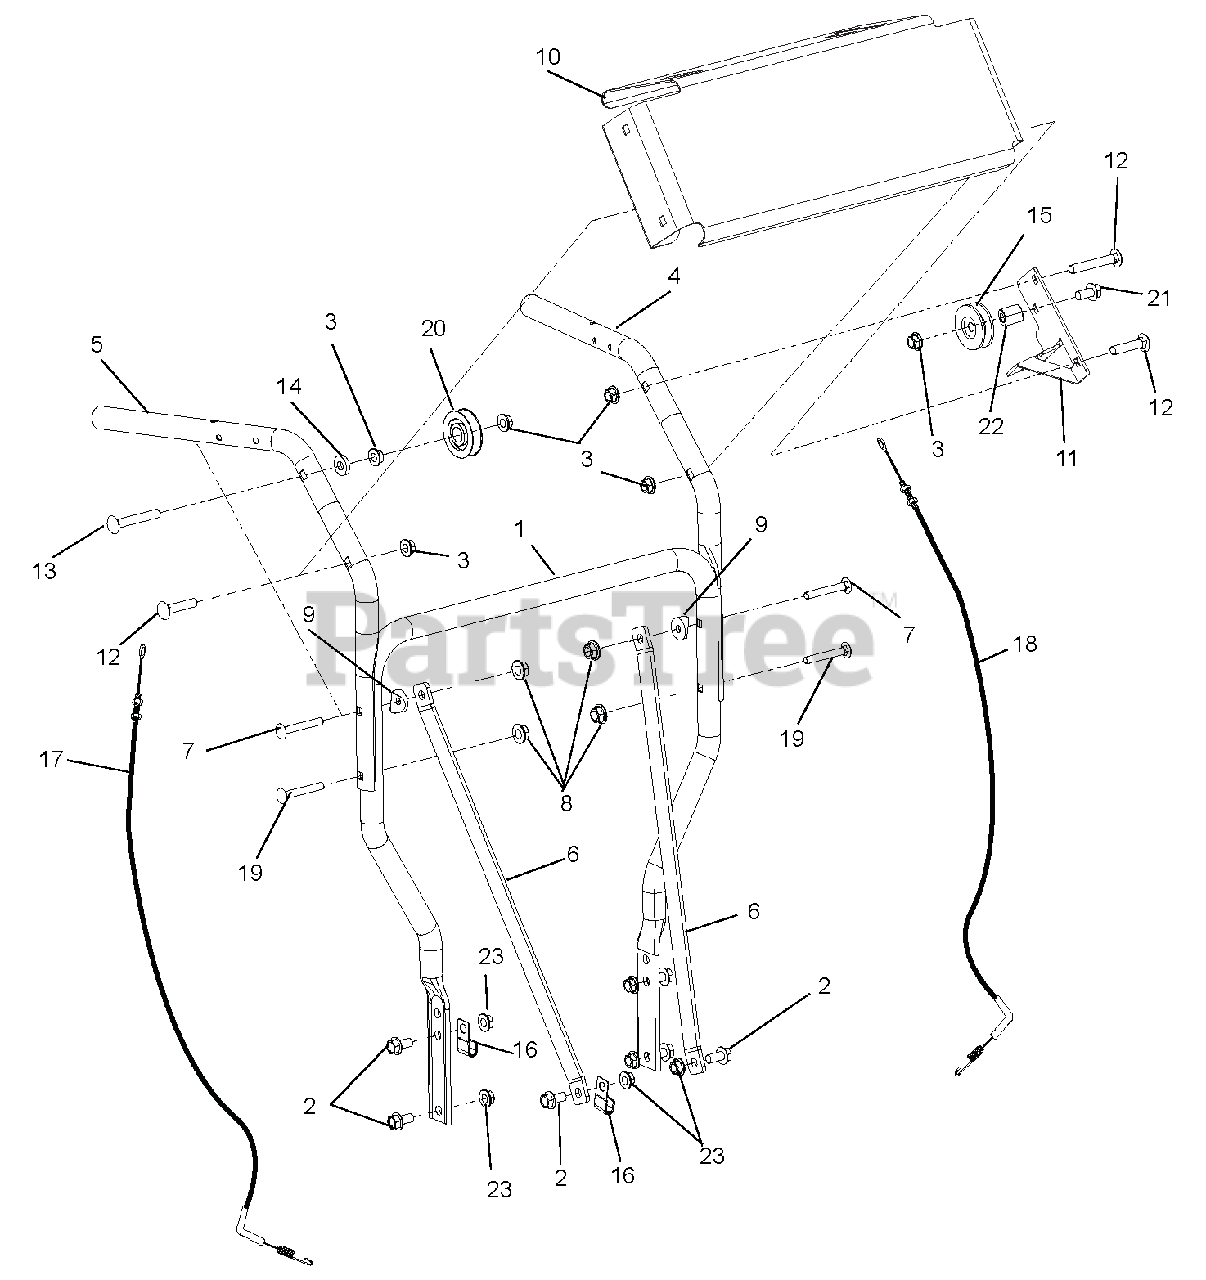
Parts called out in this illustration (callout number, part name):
1	HANDLEBAR, LOWER
2	BLT-SERHFWH .38-16X.75 YWZC
3	@NUT-LK-TOP-FLG .38-16 YWZC
4	HANDLEBAR, CE LH (WELDMENT)
5	HANDLEBAR, UPPER RH
6	BRKT-BRACE, HANDLEBARS
7	@BLT-RDHDSQNK .31-18X2.25 G5YZ
8	@NUT-LK-NYL-FLG .31-18 YWZC
9	SPACER, HANDLEBAR
10	DASH, WAW
11	MOUNT, WAW PTO CABLE (WLDMNT)
12	@BLT-RDHDSQNK .38-16X1.75 G5YZ
13	@BLT-RDHDSQNK .38-16X2.50 G5YZ
14	WSHR-FL-STL .406X1.00X.188 YWZ
15	IDLER, 3L FRONT SIDE .38X1.875
16	J-CLAMP
17	CABLE, WAW P-BRAKE
18	CABLE, WAW PTO
19	@BLT-RDHDSQNK .31-18X1.75 G5YZ
20	PULLEY, CABLE
21	@BLT-HEX .38-16X2.50 GR5 YWZC
22	SPACER, .437X1.0X1.23
23	NUT-LK-CTR-FLG .38-16 YWZC
